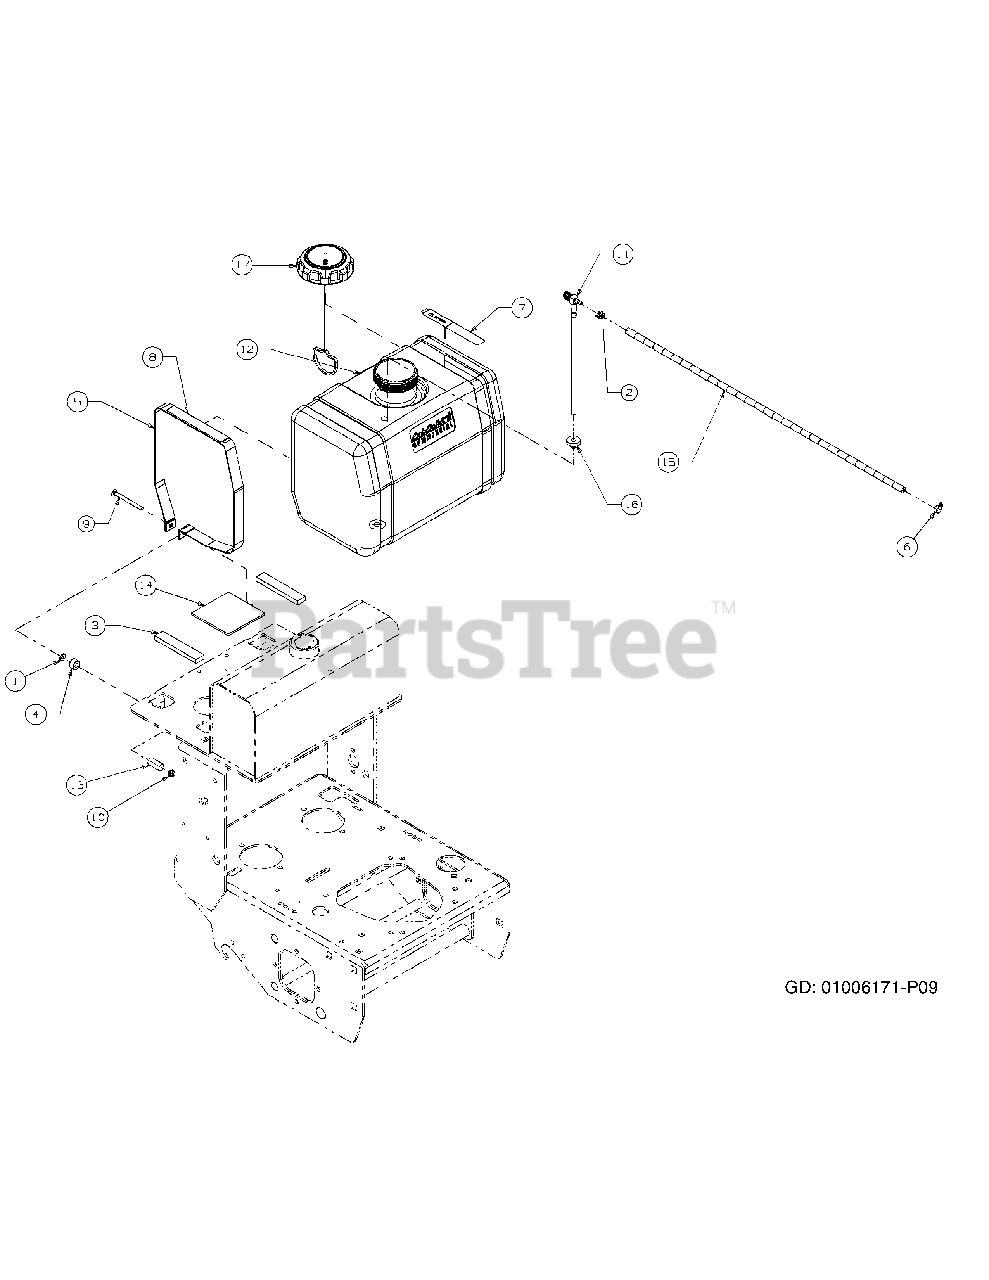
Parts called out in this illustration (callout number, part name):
1	Flat Washer, SAE 5/16
2	Uni-Clamp
3	Stop Pad, Rubber
5	Fuel Tank Strap
6	Hose Clamp, 1/4-5/8, SS
7	Mower Warning Label, Turn off Engine
8	Mower Instruction Label, Fuel Valve
9	Carriage Bolt, 1/4-20 x 3.00
10	Lock Nut, 1/4-20, Hex Flange Lock
11	Shutoff Valve
12	Fuel Tank
13	Compression Spring, .625 OD x .390 ID
14	Rubber Strip
15	Fuel Hose, 18"
16	Grommet Fuel Tank
17	Fuel Cap, 3.5, Tethered
